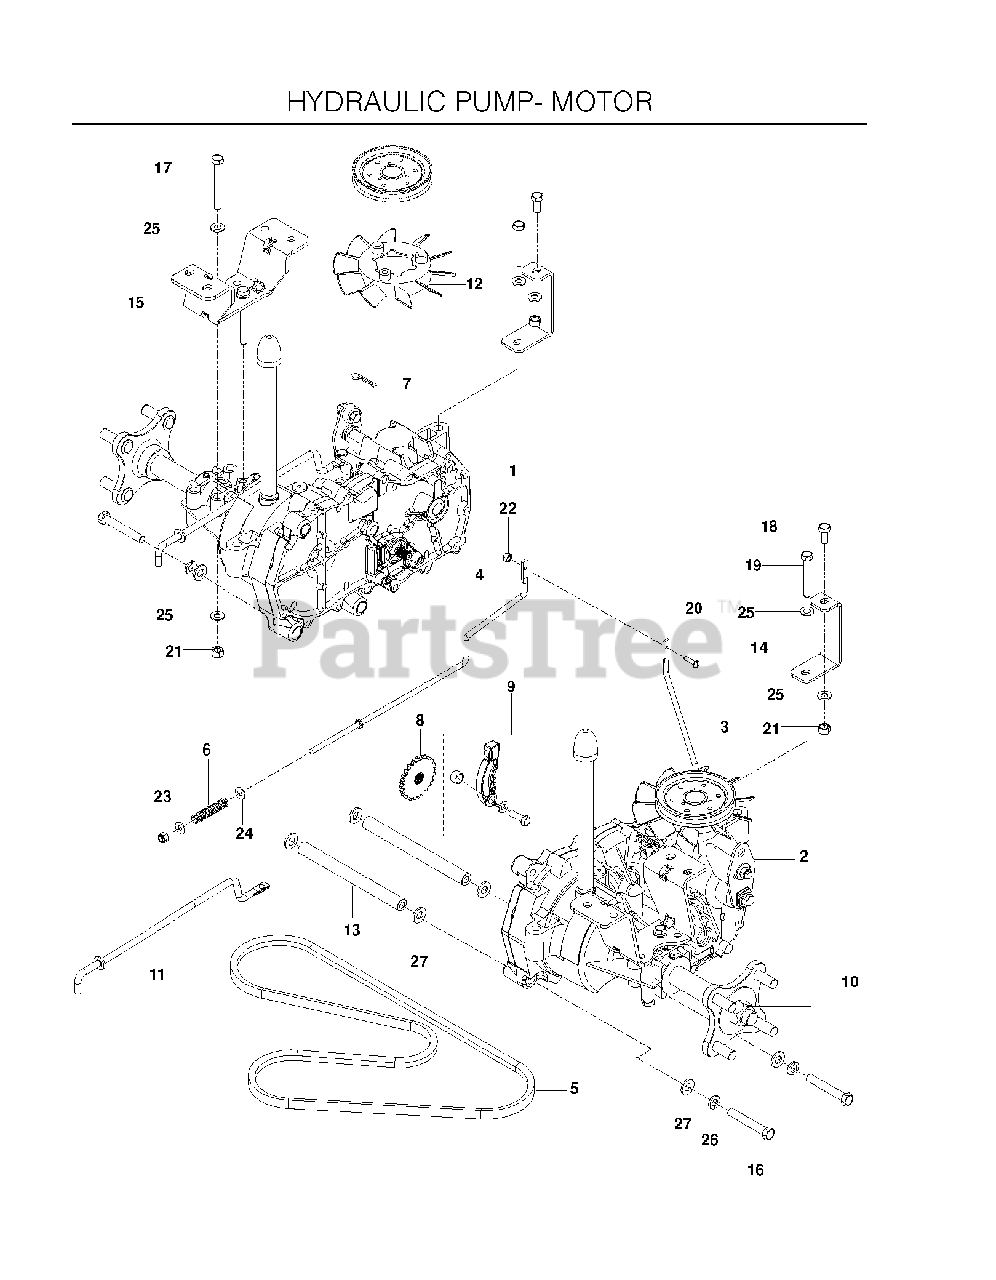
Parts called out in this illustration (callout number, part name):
1	HG_EZT, LT
2	HG_EZT, RT
3	LINKAGE.BRAKE.LT
4	LINKAGE, BRAKE RT
5	BELT, HYDRO PUMP
7	HAIRPIN #2
8	HG_DISC COG BRAKE
9	HG_KIT BRAKE ARM (EZT)
10	HG_KIT, HYDRO-GEAR HUB
11	LINKAGE, BYPASS, EZT
12	HG_HYDRO FAN
13	SPACER TUBE, EZT
14	SUPPORT FRT TRANS, BLK
15	EZT MOUNT, REAR, BLACK
16	HCS 3/8C X 2 1/2
17	HCS 5/16C X 2-3/4
18	HCS 5/16C X 3/4
19	CAPSCREW
20	SCR #10-24 X 3/4
21	NUT 5/16 NYLOC
22	NUT 10-24 NYLOC
23	NUT 1/4-20 NYLOC
24	WASHER 1/4 SAE
25	FLAT WASHER 5/16 SAE
26	SLW 3/8 STD
27	WASHER 3/8 SAE FLAT
